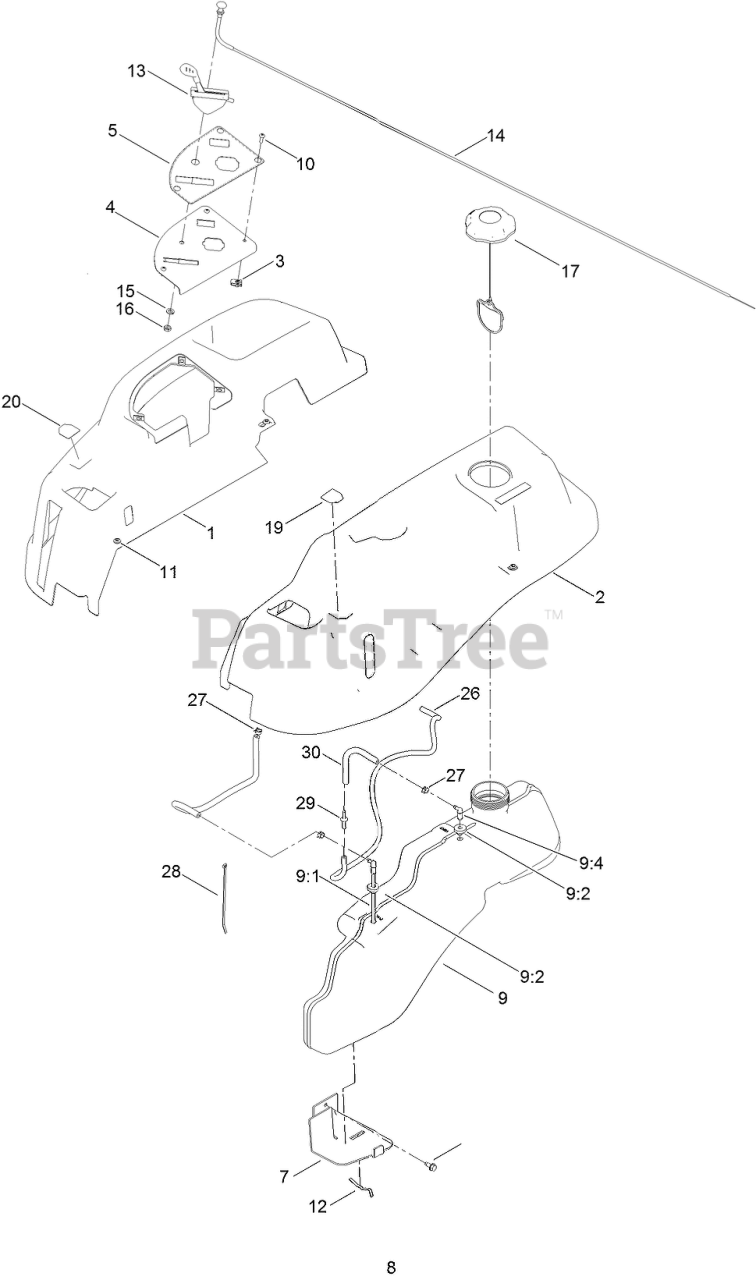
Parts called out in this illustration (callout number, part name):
1	POD-RH
2	POD-LH
4	PLATE-CONTROL
5	DECAL-PANEL, CONTROL
7	SUPPORT-TANK, FRONT
8	SCREW-HWHTF
9	FUEL TANK ASM
9:1	CONNECTOR-ELBOW, 90 DEG
9:2	BUSHING
9:4	FITTING-PLASTIC
10	SCREW-PRH
11	SCREW-SHOULDER
12	SPRING
13	CABLE-THROTTLE
14	CABLE-CHOKE
15	WASHER-LOCK
16	NUT-HJ
17	CAP-FUEL, RATCHETING
19	DECAL-LEVER, CONTROL (LH)
20	DECAL-LEVER, CONTROL (RH)
26	HOSE-FUEL
27	CLAMP-HOSE
28	TIE-CABLE
29	ADAPTOR-ORIFICE
30	HOSE-FUEL
